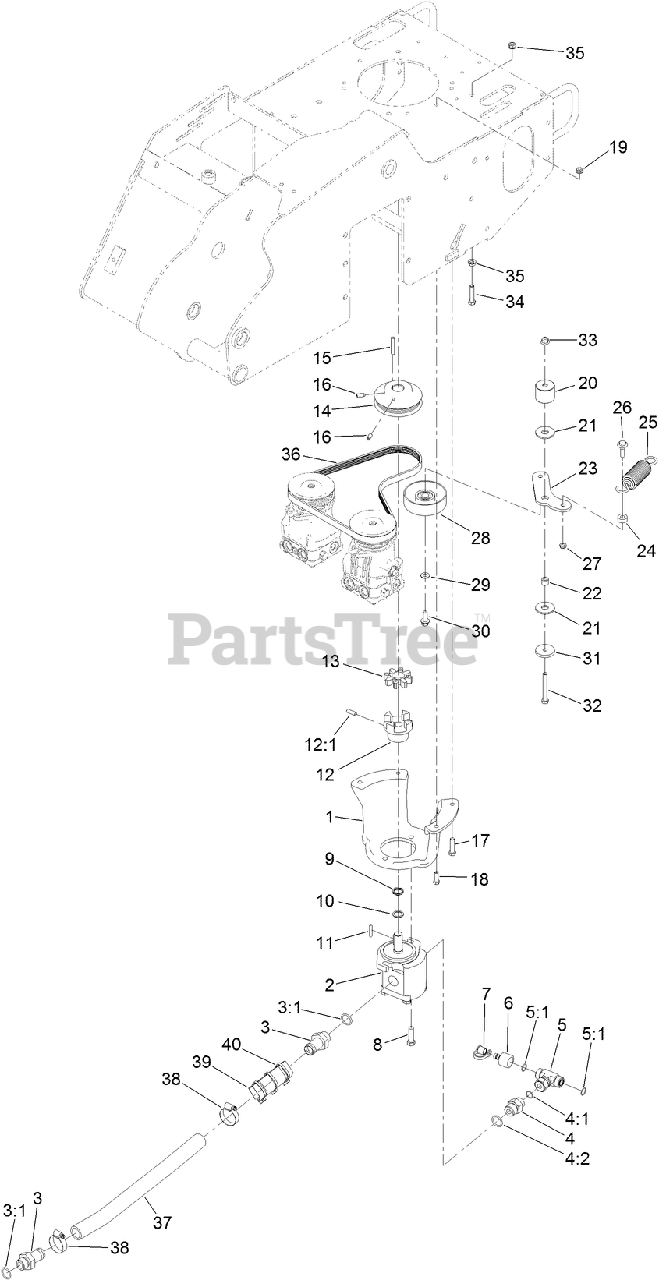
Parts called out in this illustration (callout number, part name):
1	MOUNT-PUMP
2	GEAR PUMP ASM
3	FITTING
3:1	O-RING
4	FITTING-STRAIGHT
4:1	O-RING
4:2	O-RING
5	FITTING-HYD, TEE
5:1	O-RING
6	NIPPLE
7	CAP-DUST
8	SCREW-HH
9	WASHER-WAVE
10	WASHER-THRUST
11	KEY-SQUARE
12	COUPLER-FLEX
12:1	SCREW-SET
13	COUPLER-SPIDER
14	PULLEY-ENGINE
15	KEY-SQUARE
16	SCREW-SET, HSH
17	SCREW-HH
18	SCREW-HH
19	NUT-HF
20	SPACER-IDLER
21	WASHER-FRICTION, COMPOSITE
22	BUSHING-LEVER, LIFT
23	ARM-IDLER
24	SPACER
25	SPRING-EXTENSION
26	SCREW-SHOULDER, HWH
27	NUT-LOCK, NI
28	PULLEY-IDLER
29	WASHER-FLAT
30	SCREW-HHF
31	WASHER-PLAIN
32	SCREW-HH
33	NUT-HF, NI
34	SCREW-HH
35	NUT-HHF, WHIZ
36	BELT-V
37	HOSE-SUCTION
39	PROTECTOR-HOSE
40	TIE-CABLE
